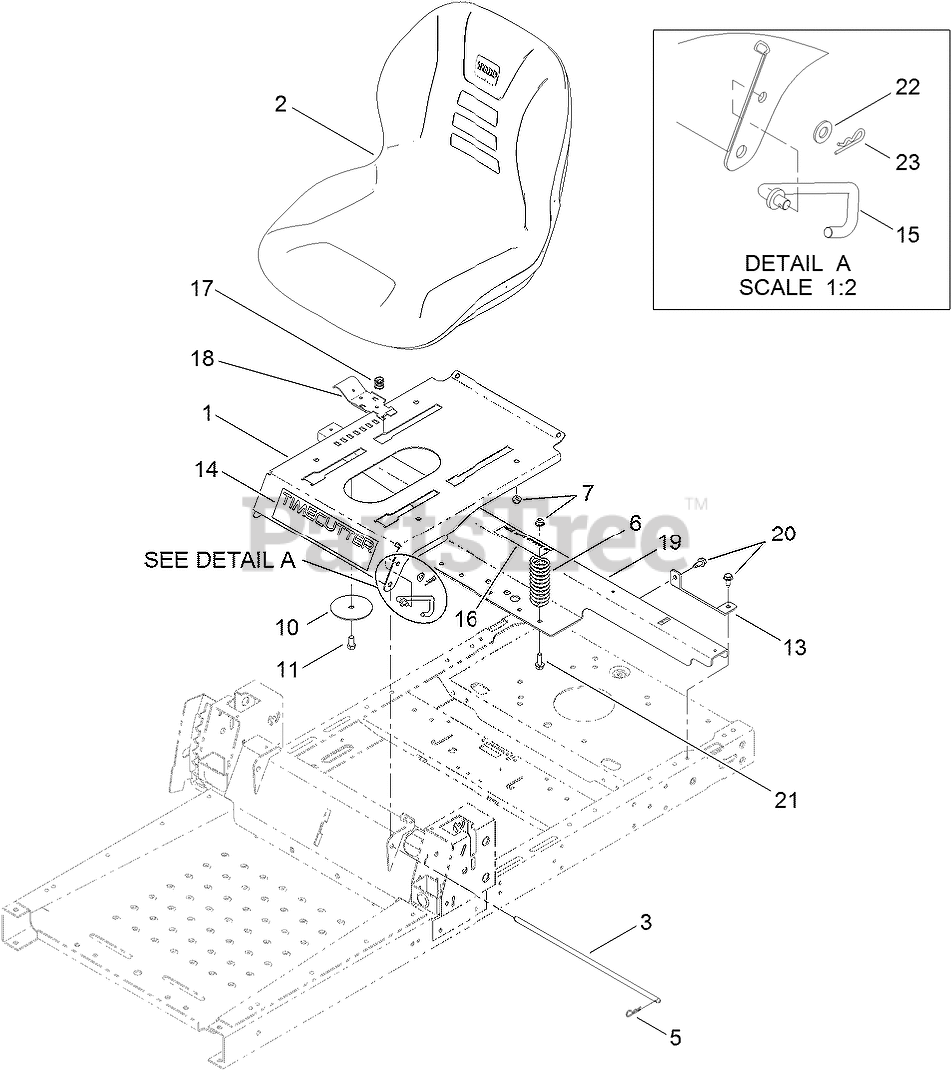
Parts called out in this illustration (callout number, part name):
1	PAN-SEAT
2	SEAT-18 INCH
3	ROD-STOP
5	PIN-COTTER
6	SPRING-COMPRESSION
7	NUT-HF, NI
10	WASHER-SEAT
11	SCREW-HH
13	SUPPORT-TANK, REAR
14	DECAL-TIMECUTTER
15	STOP-SEAT
16	DECAL-SERVICE, CE
17	SPRING-COMPRESSION
18	LATCH-SEAT
19	SUPPORT-POD
20	SCREW-HWHTF
21	SCREW-HHF
22	WASHER-PLAIN
23	PIN-COTTER
